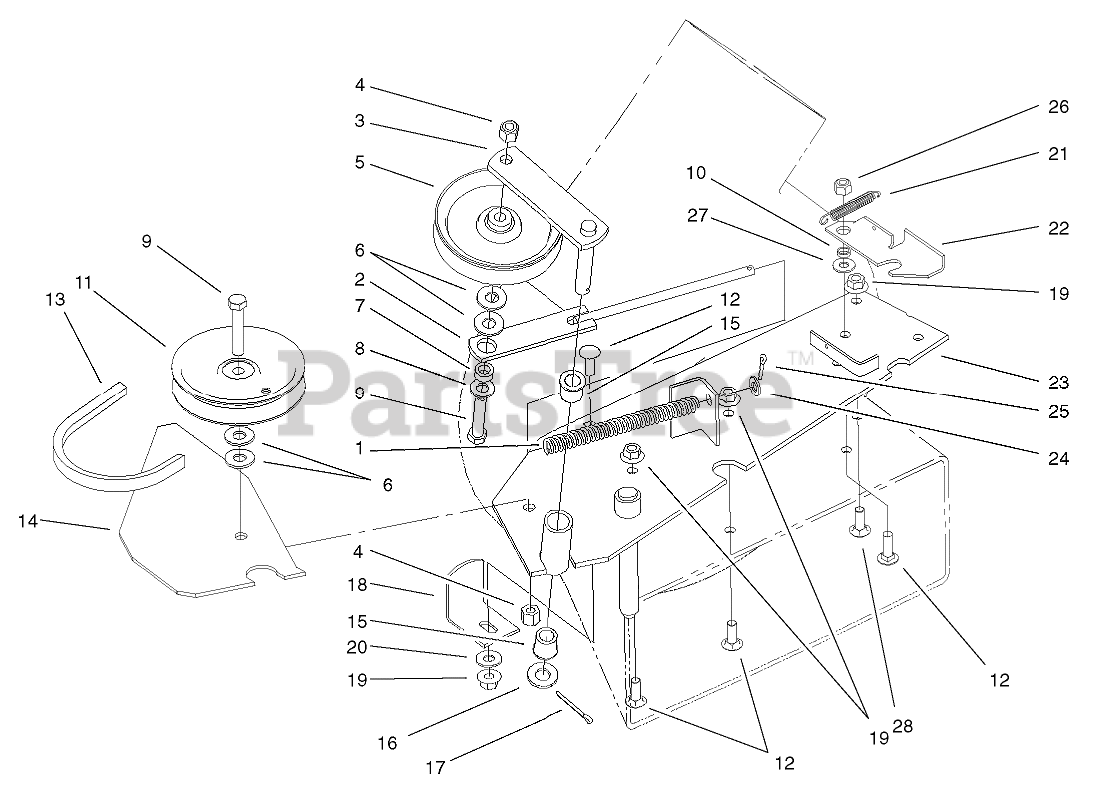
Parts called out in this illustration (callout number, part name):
1	SPRING-COMPRESSION
2	SPRING-ROD
3	IDLER ARM ASM
4	NUT-LOCK, NI
5	PULLEY-IDLER
6	WASHER-FLAT
7	SPACER
8	WASHER-FLAT
9	SCREW-HH
10	BUSHING
11	PULLEY-IDLER
12	SCREW-CARR
13	BELT-V
14	SUPPORT-SHIELD, BELT
15	BUSHING
16	WASHER-FLAT
17	PIN-COTTER
18	BRACKET-SUPPORT, HOUSING
19	NUT-HF
20	WASHER-FLAT
21	SPRING-EXTENSION
22	Latch-Blower
23	Mounting-Blower
24	WASHER-PLAIN
25	PIN-COTTER
26	NUT-LOCK, NI
27	WASHER-FLAT
28	BOLT-CARR
